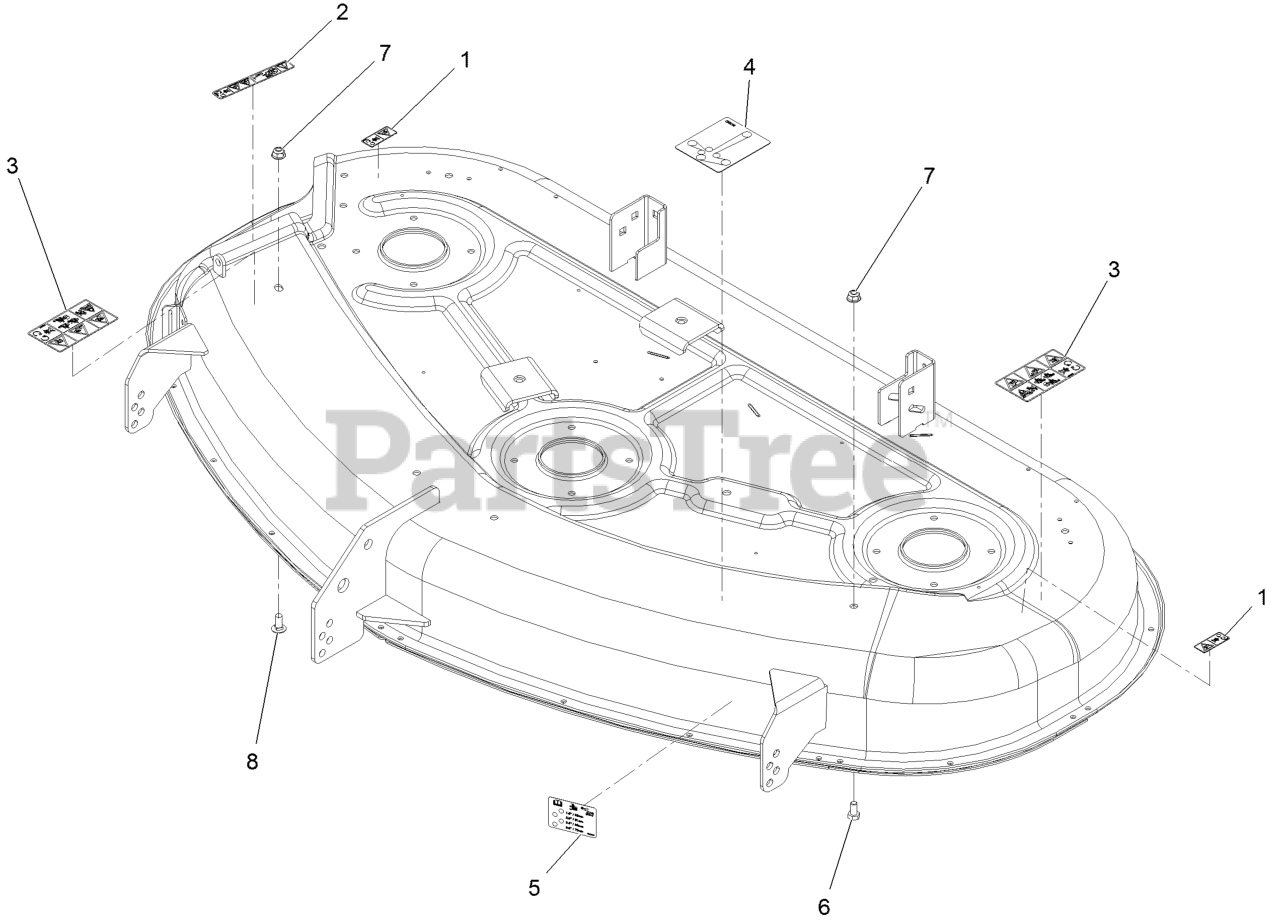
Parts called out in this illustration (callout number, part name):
1	DECAL-DANGER
2	DECAL-DANGER
3	DECAL-DANGER
4	DECAL-ROUTING, BELT
5	DECAL-SCALP, ANTI
6	SCREW-HH
7	NUT-HF, NI
8	SCREW-CARR
